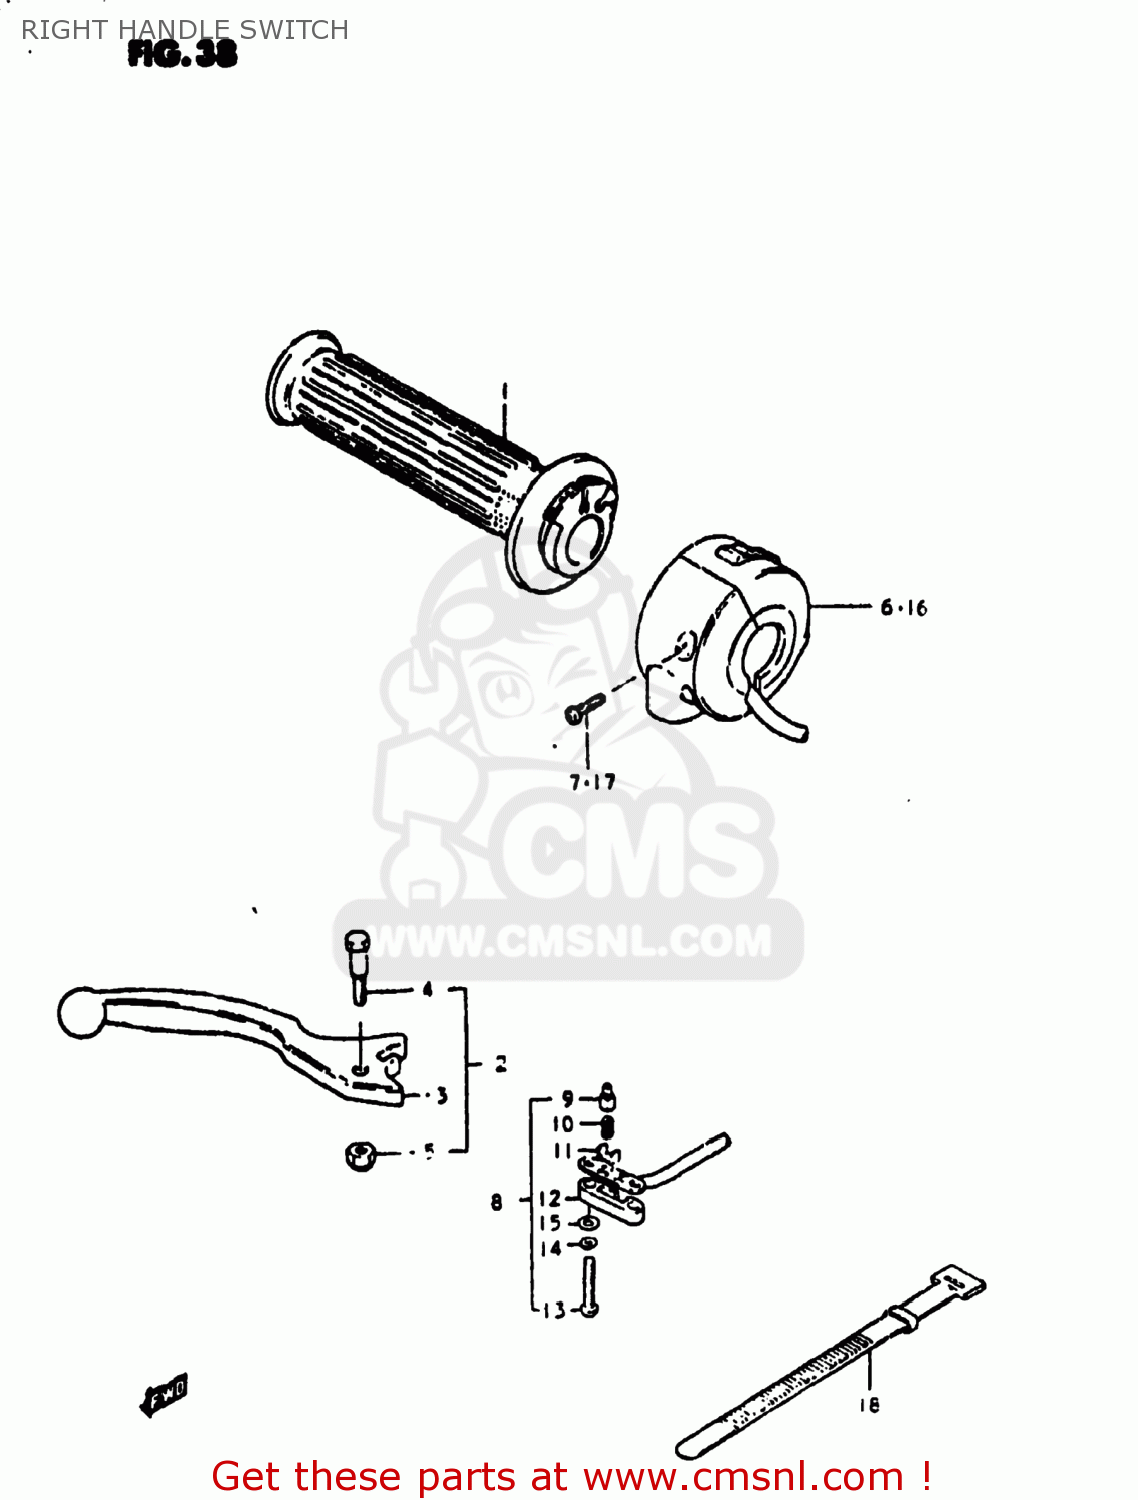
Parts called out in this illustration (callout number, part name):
1	GRIP,THROTTLE
2	LEVER ASSEMBLY,BRAKE
3	LEVER,BRAKE
4	BOLT
5	NUT 6MM
6	SWITCH ASSEMBLY,HANDLE,RIGHT
7	SCREW
8	SWITCH ASSEMBLY
9	HOLDER
10	SPRING
11	PLATE
12	COVER,FR BK TERMINAL BASE
13	SCREW
14	LOCK WASHER
15	WASHER
16	SWITCH ASSEMBLY,HANDLE,RIGHT
17	SCREW
18	CLAMP(L:120)
